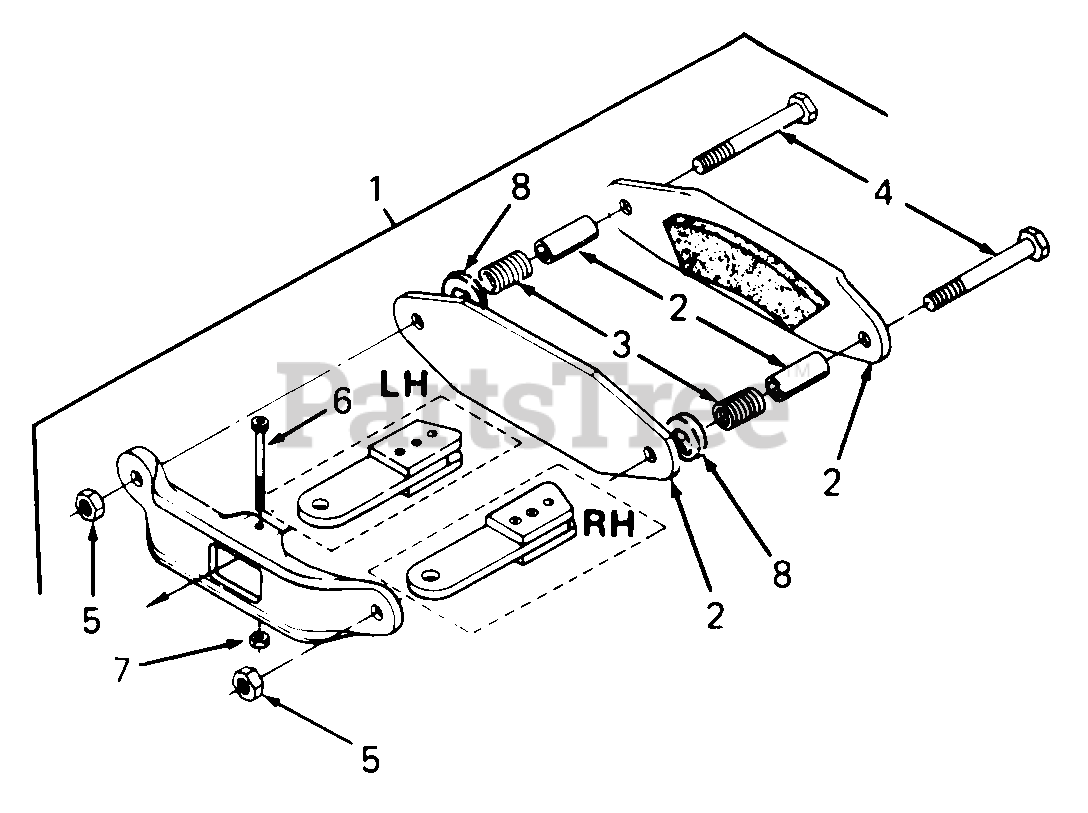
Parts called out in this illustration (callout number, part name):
1	Kit, Brake Caliper
2	Puck Kit, Brake
3	Spring, Compression
4	Screw, Hex Cap, 3/8-24 X 2.25 Lg
5	Nut, Hex Lock, 3/8-24 GR5
6	Screw, Socket Hd Shld, 1/4-20 X 1.25 Lg
7	Nut, Hex Top Lock Jam, 1/4-20 GR5
8	Washer, Flat, .390 X 1.0 X .030 Thk HDN
